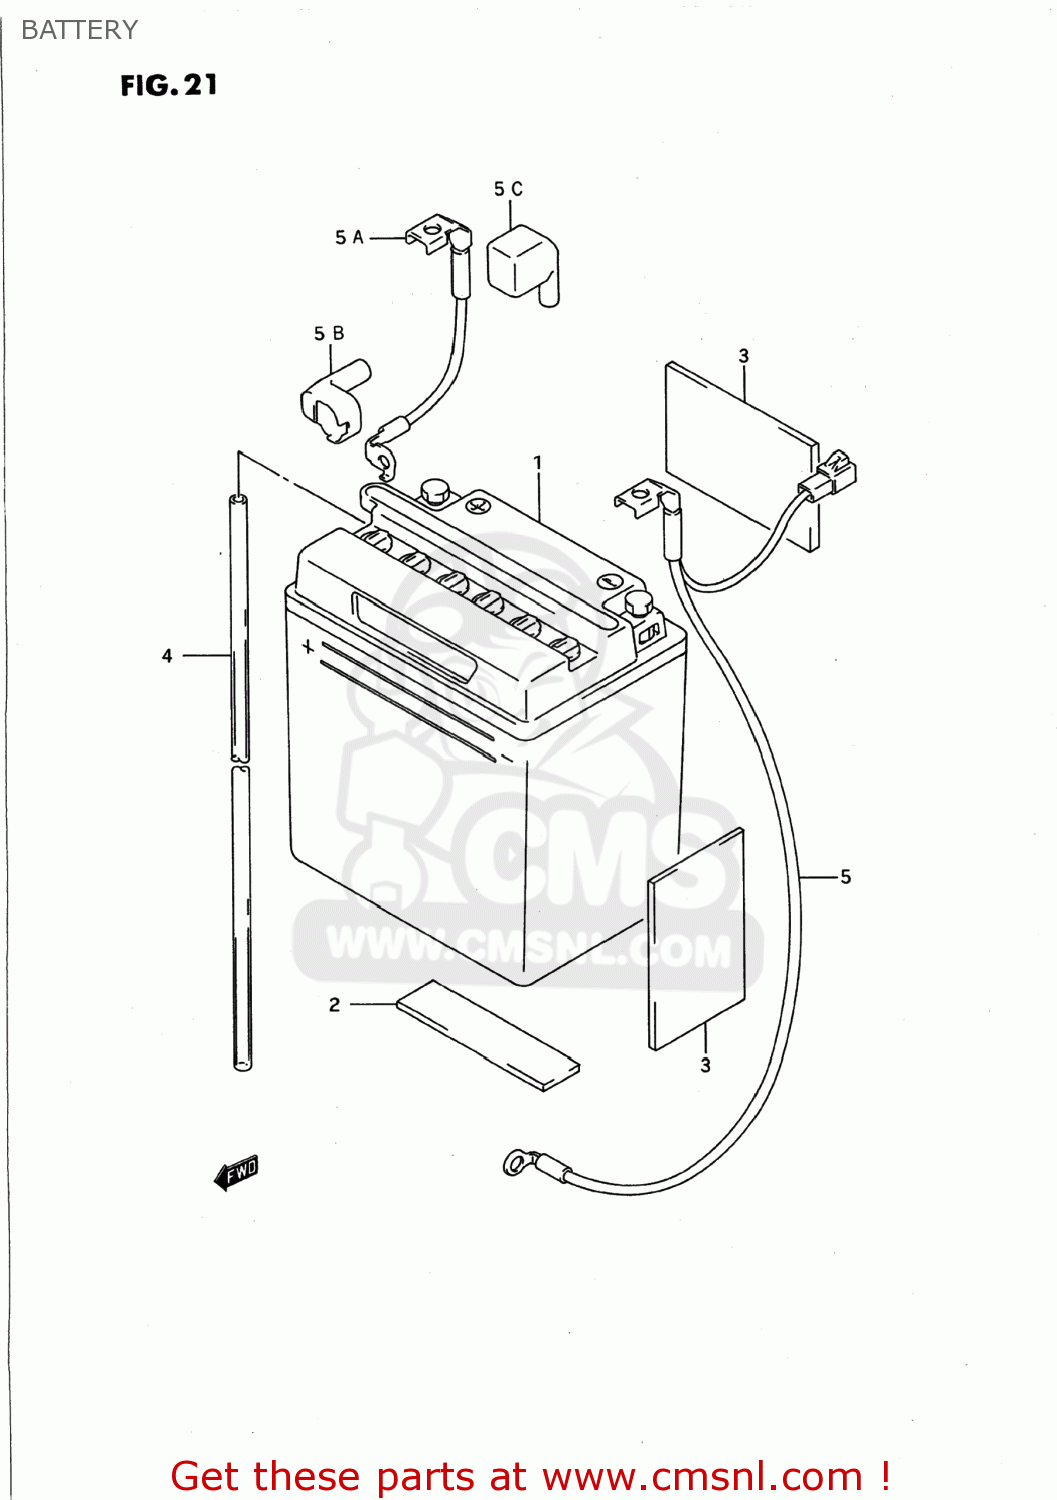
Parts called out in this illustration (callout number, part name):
1	BATTERY ASSY (12V)
2	CUSHION,BATTERY(80X27X3)
3	PROTECTOR(170X95X3.0)
4	HOSE,BATTERY EXHAUST(L:780)
5	WIRE,BATTERY MINUS LEAD
5A	WIRE,BATTERY PLUS LEAD
5B	CAP,STARTER RELAY TERMINAL
5C	CAP,BATTERY PLUS TERMINAL
